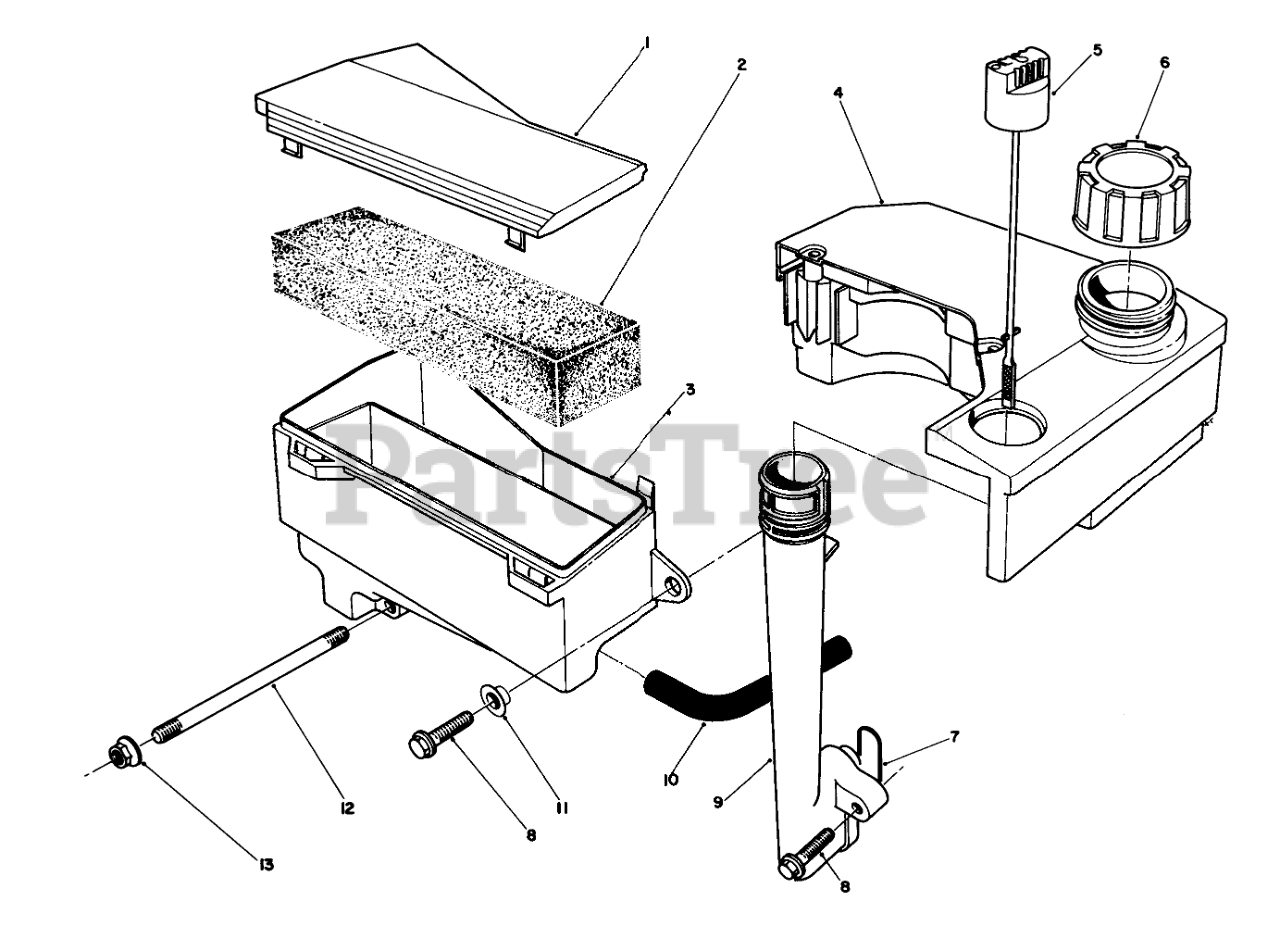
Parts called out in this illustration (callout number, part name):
1	AIR CLEANER CAP
3	Air Cleaner Assembly (Incl. Ref. #1)
4	TANK ASM
5	Dipstick
6	GAS CAP ASM
7	O-RING
11	SPACER
12	Stud-Carburetor
